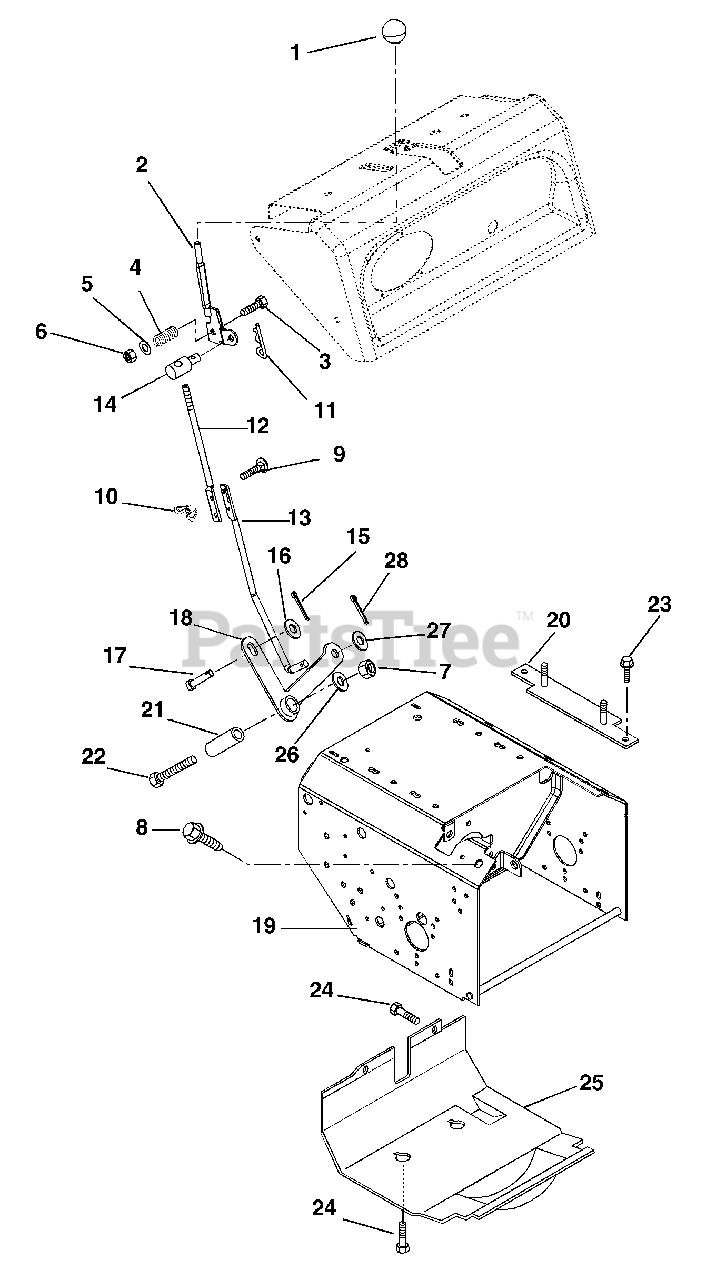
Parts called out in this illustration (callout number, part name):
1	KNOB,BALL -BLACK 1.47" .375-16
2	LEVER, SHIFT
3	@BLT-HEX .38-16X2.25 GR5 YWZC
4	SG-COMP .125X.781X1.250
5	@WSHR-FL-STL.438X1.00X.083 YWZ
6	@NUT-LK-CTR .38-16 YWZC
7	@NUT-LK-CTR .31-18 YWZC
8	BLT-SERHFWH .38-16X.75 YWZC
9	@BLT-RDHDSQNK .25-20X1.00 G5YZ
10	NUT-LK WING .250-20 YWZC
11	PIN-HAIR INT .08X.18X1.18 YWZC
12	ROD, SHIFT-UPPER
13	ROD, SHIFT-LOWER
14	PIVOT, ROD (TRUNNION ) .50
15	@PIN-CTR .09X.75 EXTPRSQCT YWZ
16	WSHR-FL-STL .382X.812X.023YWZC
17	CLEVIS PIN
18	ARM, SHIFT
19	MAIN FRAME
20	BOLT STRAP
21	BSHG-SLV .328X.50X.75
22	@BLT-HEX .31-18X1.25 GR5 YWZC
23	@SCR-TAP .25-20X.37 HWH YWZ TR
24	@SCR-TAP .31-18X.50 HWH TR YWZ
25	COVER, BOTTOM
26	@WSHR-FL-STL.344X.688X.065YWZC
27	@WSHR-FL-STL.531X1.06X.095YWZC
28	@PIN-CTR .12X.75 EXTPRSQCT YWZ
